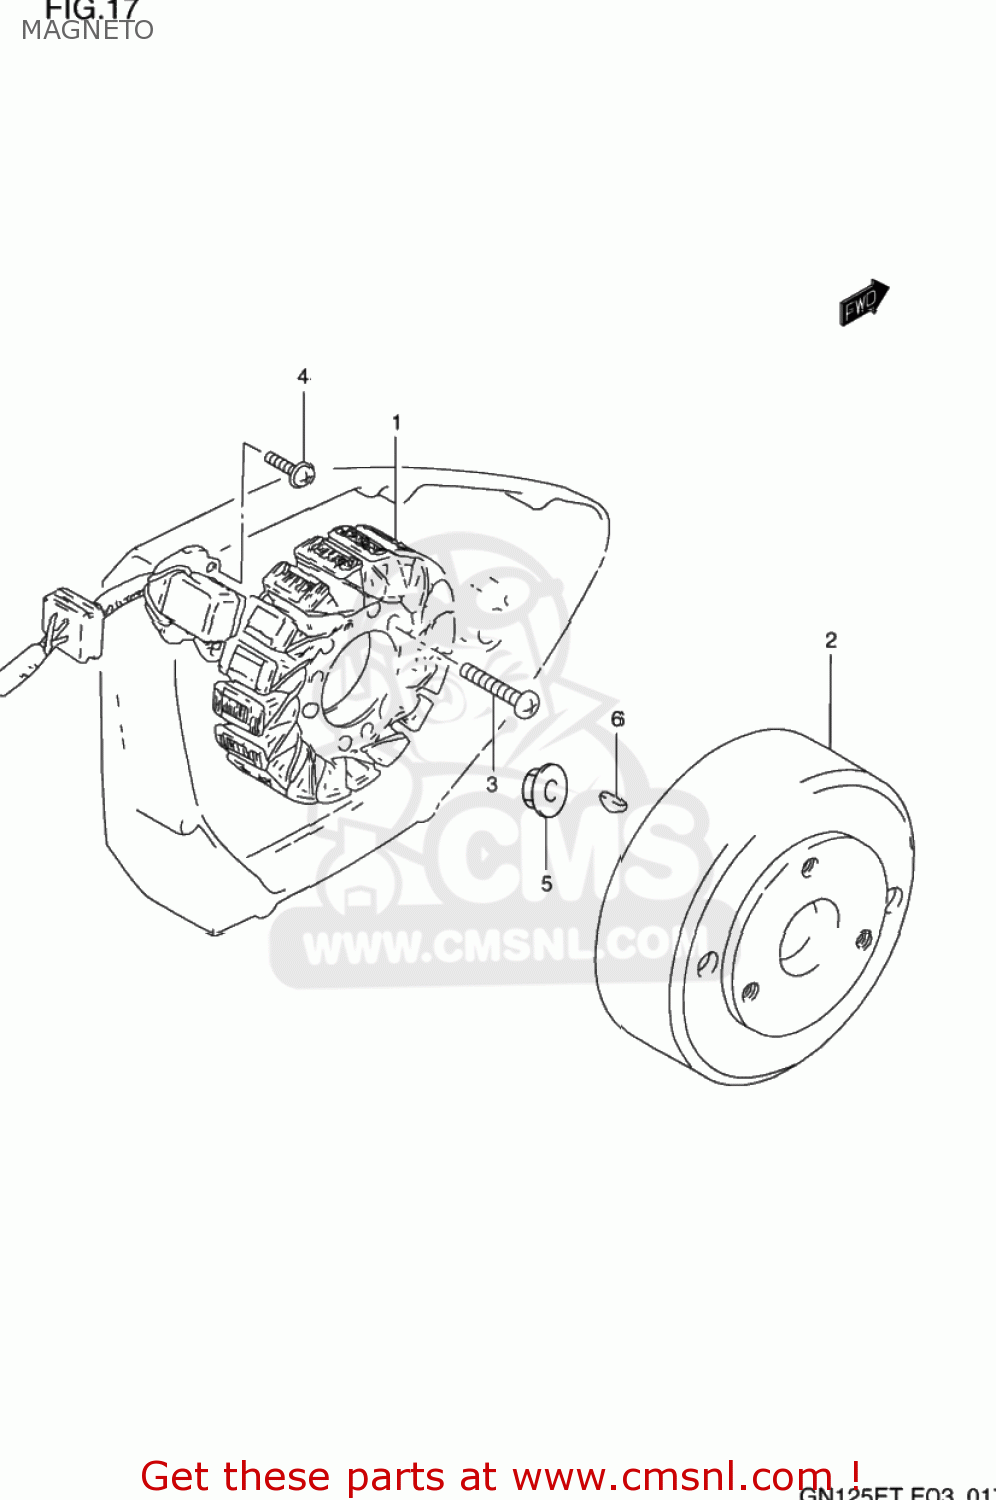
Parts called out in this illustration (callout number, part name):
1	STARTER ASSY
2	ROTOR,FLYWHEEL
3	SCREW
4	SCREW
5	NUT
6	KEY
